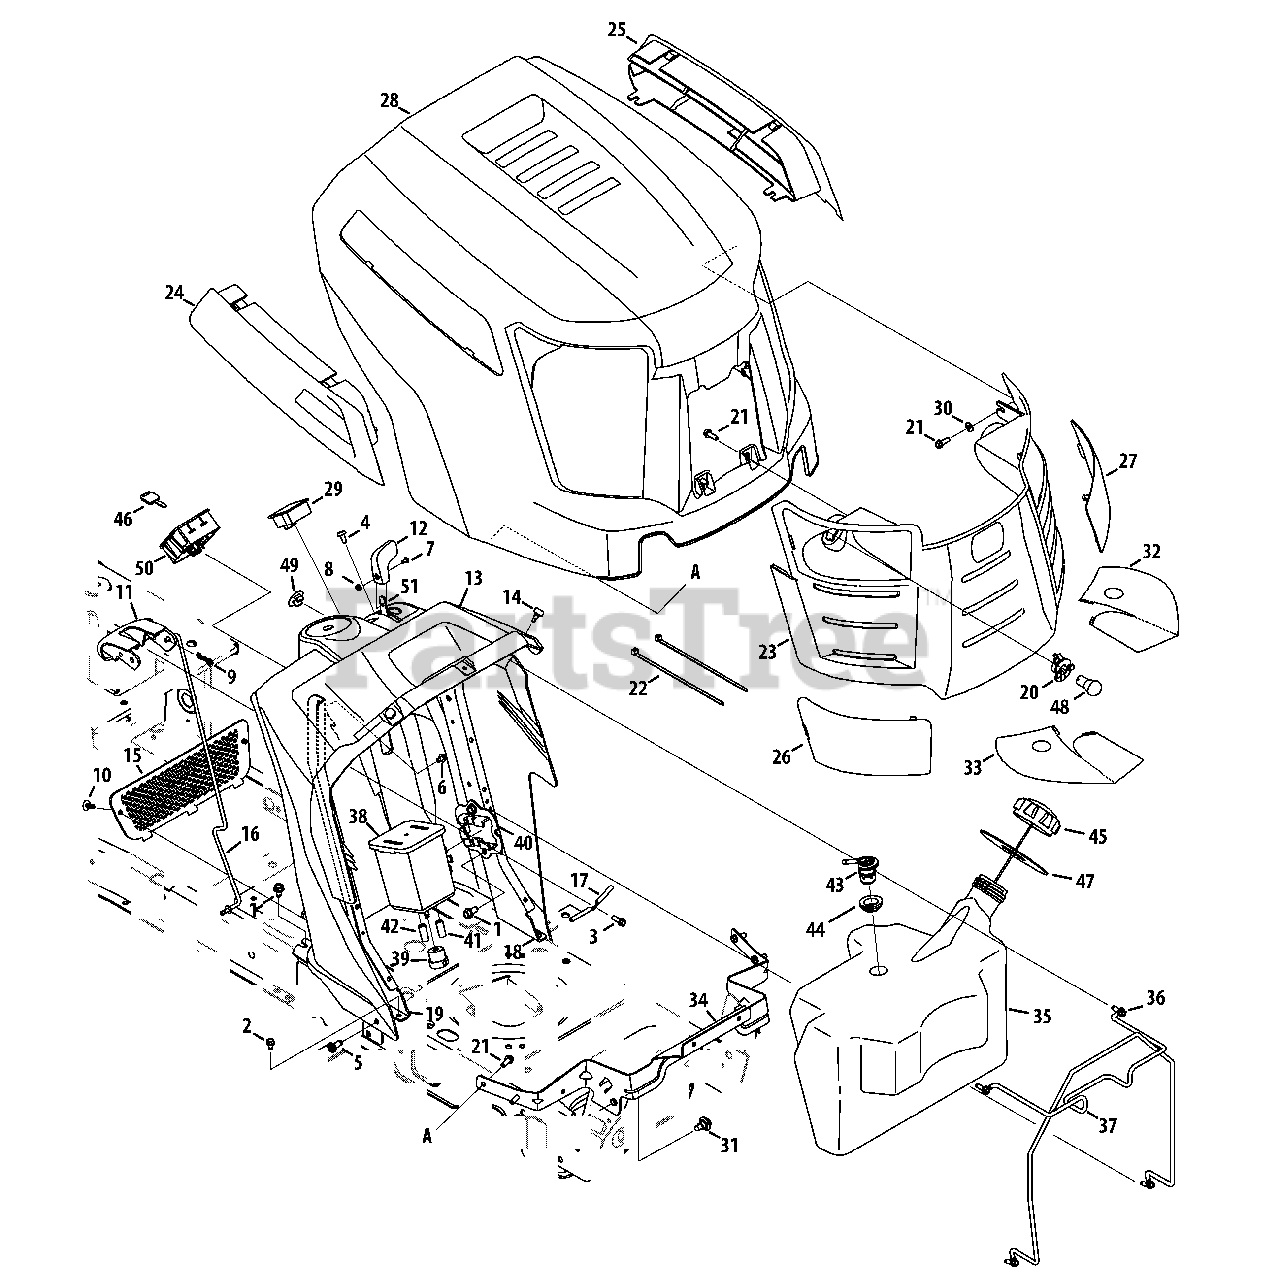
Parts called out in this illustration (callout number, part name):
1	Screw, Self-tapping, 5/16-18, .750
2	Screw, Self-tapping, 1/4-20, 0.500
3	Screw, HL, 1/4-15, 0.750
4	Screw, Ab, 1/4-14, 0.625,
5	Screw, Self-tapping, 5/16-18, 0.750,
6	Screw, Self-tapping, 1/4-20 x .625
7	Screw, Mach, #8-32, 0.375
8	Nut, Hex, #8-32
9	Pin, Cotter, Bow-Tie 72
10	Clip, Ratchet, .250 Dia
11	Lever, Dash, Cruise/Brake
12	Knob, Throttle
13	Dash Panel, A-Style, Man PTO
14	Bumper, .62 Dia X .3
16	Rod, Control, Latch Cub
17	Rod, Lever, Bent
18	Support, Dash, Plate LH
19	Support, Dash, Plate RH
20	Socket, Lamp
21	Screw, 1/4 Dia, .750
22	Tie, Cable, Push Mount 7.5 Lg
23	Grille Ass’y (Incl. 26, 27, 32 & 33)
24	Scoop, Hood, RH A-Style
25	Scoop, Hood, LH A-Style
26	Lens, Hood, RH A-Style
27	Lens, Hood, LH A-Style
28	Hood, A-Style
29	Meter, Indicator
30	Washer, Flat, .271, .630, .065
31	Screw, Shoulder, .43x.29, 5/16-18
32	Reflector, Cub A Style, LH
33	Reflector, Cub A Style, RH
34	Bracket, Pivot, Hood A-Style
35	Tank, Fuel, 3.30 Gal.
36	Screw, Self-tapping, 1/4-20, .625
37	Rod, Support, Fuel Tank
38	Canister, Carbon, 5 Gallon (CA)
39	Filter, Vent, Canister (CA)
40	Bracket, Adapter, Canister (CA)
41	Hose, Fuel, Low Perm, 3/16 Wht (CA)
42	Hose, Fuel, Low Perm, 7/32 Yel (CA)
43	Valve, Rollover Grommet
44	Grommet, Rubber, 23.0 ID
45	Cap, Fuel
45	Cap, Fuel Carb
46	Key, Assembly
47	Gasket, Fuel Tank
48	Lamp, 12v
49	Plug, Choke
50	Module Switch, Ignition
51	Cable, Throttle/Choke, 28"
